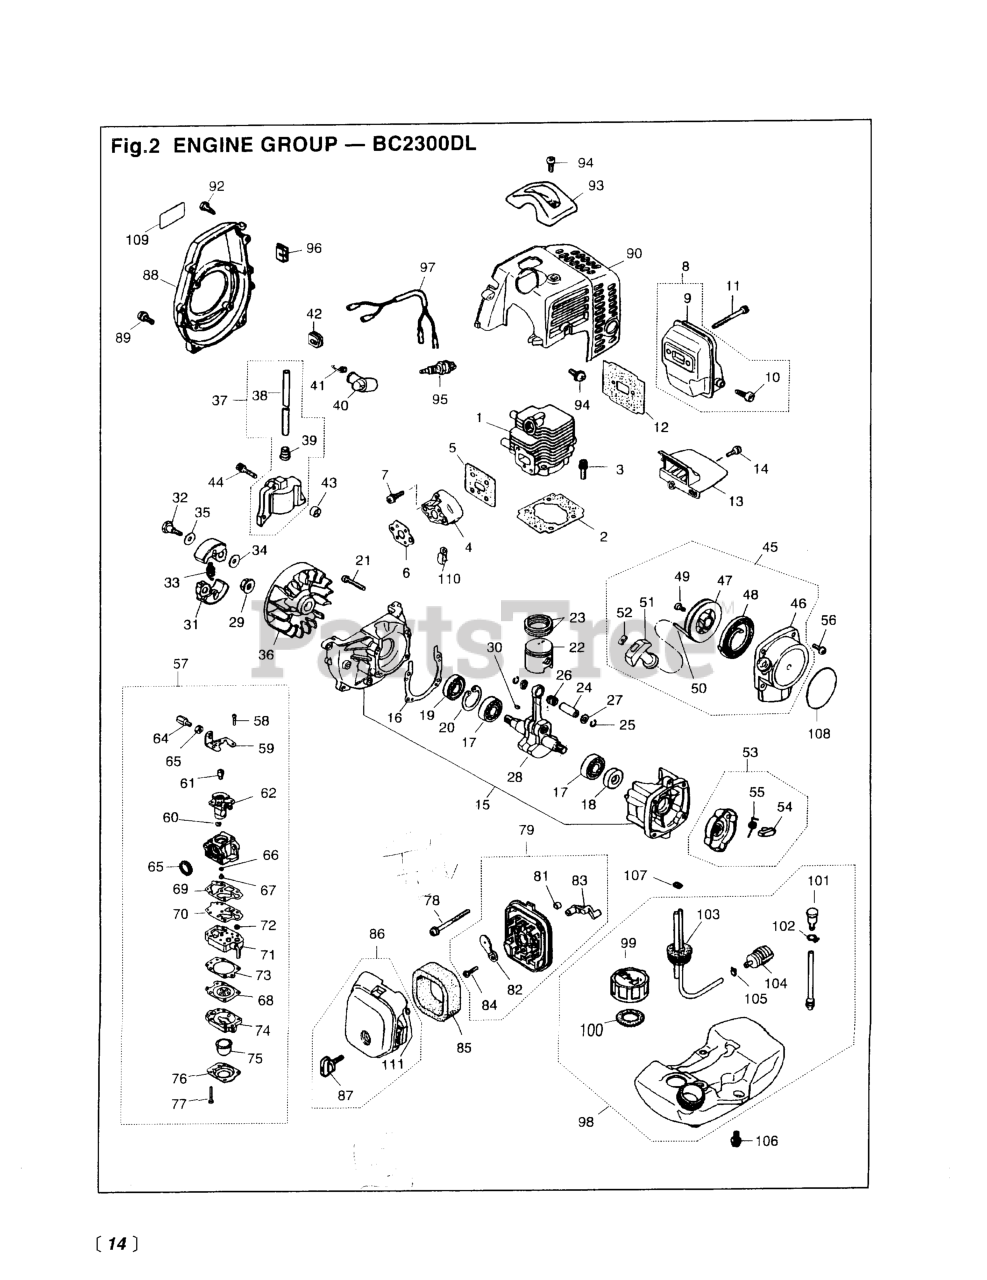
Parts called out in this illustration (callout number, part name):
1	CYLINDER
3	BOLT, M5 X 22
7	SCREW, M5X20 (RPLS.1400-75510)
9	MUFFLER ASSY (USE 5913-15100)
10	ARRESTER (RPLS 5850-15140)
11	BOLT, M5 x 50
12	GASKET, MUFFLER
14	SCREW, M4 X 16
15	CRANKCASE
17	BEARING
18	SEAL, OIL (RPLS 1100-21210)
19	SEAL, OIL (RPLS 1140-21220)
20	RING, SNAP, M28 x 1.2
21	BOLT, M5 X 30
22	PISTON (REPLACES 1140-41110)
23	RING, PISTON (RPLS 1850-41210)
24	PIN, PISTON 5x8x26
25	RING, SNAP (RPLS 1101-41320)
27	WASHER
28	CRANKSHAFT (RPLS 1850-42000)
30	KEY
32	BOLT
33	SPRING, CLUTCH (RPLS-51220)
34	WASHER, FLAT (USE 182303)
38	CORD
39	CAP
41	SPRING
42	GROMMET
43	SPACER (RPLS -71260)
44	BOLT
45	RECOIL ASSEMBLY
46	CASE
47	REEL
48	SPRING, SPIRAL
49	SCREW (RPLS -75150)
51	KNOB
52	PLATE, STOPPER
53	PULLEY ASSY (RPLS -75210)
54	RATCHET (RPLS 1850-75220)
55	SPRING, RETURN
56	SCREW, M4 X 16
57	CARBURETOR
58	SCREW
60	RING
61	SWIVEL
62	VALVE ASSY
63	SCREW, CABLE ADJUSTER
64	NUT, CABLE ADJUSTER
65	RING, PACKING
66	RING, O
67	JET
68	DIAPHRAGM (USE 4810-81260)
69	GASKET, PUMP
70	DIAPHRAGM
71	BODY, PUMP
73	GASKET, DIAPHRAGM
74	BODY, PURGE
75	PUMP, PRIMING
76	COVER, PUMP
77	SCREW
78	SCREW, M5 x 60
81	SLEEVE
82	PLATE, CHOKE (RPLS-82130)
83	LEVER, CHOKE
84	SCREW (REPLACES 50030272)
85	ELEMENT
87	KNOB (RPLS -82220)
88	COVER, FAN (RPLS-31110)
89	SCREW, M5X20 (RPLS.1400-75510)
91	SCREW, M5 x 12
92	SCREW, HOUSING
93	GUARD, PLUG
94	SCREW,M5 X 14 (RPLS 1400-15510
97	CORD COMP (RPLS -73200)
99	CAP (RPLS -85200)
100	PACKING
102	CLIP
103	PIPE COMPLETE
104	FILTER (RPLS 1850-85300)
105	CLIP (REPLACES 2841-31280)
106	SCREW
107	CLIP
108	LABEL, RECOIL (RPLS -91121)
110	CLAMP
111	RING
NI	BODY
